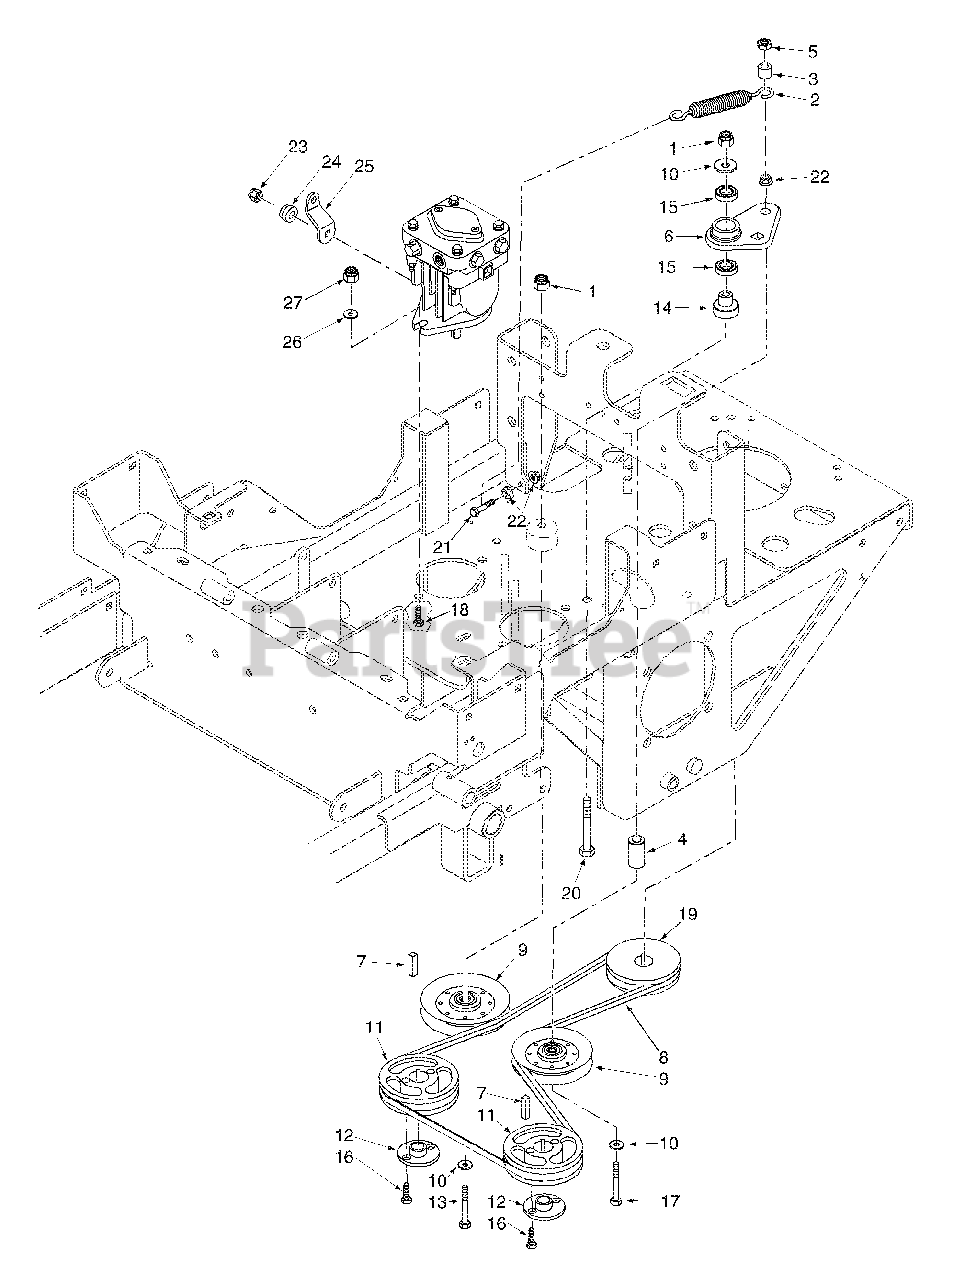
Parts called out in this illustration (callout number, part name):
1	Nut, Elastic Stop 3/8-16
2	Spring, SZC Pump Drive
3	Sleeve
4	Spacer, Pump Idler
5	Nut, Center Lock 3/8-16
6	Idler Arm Assembly, Pump Drive
7	Key, 5 x 5 x 25mm
8	Belt, Pump Drive SZC
9	Pulley, Idler 3" Dia.
10	Flatwasher, 3/8-.391 x .938 x .105 HD
11	Pulley, 5.45 O.D. Tapered Bore
12	Hub, Tapered, 15mm Bore
13	Bolt, Hex Head 3/8-16 x 2"
14	Pivot, Idler Short
15	Bearing
16	Bolt, Hex Head 1/4-20 x 1" Grade 8 Black
17	Bolt, Hex Head 3/8-16 x 3-1/4"
18	Bolt, Hex Head 3/8-16 x 1-1/2"
19	Pulley, 5.45" Dia. 1" Bore
20	Bolt, Hex Head 3/8-16 x 2-1/2"
21	Bolt, Hex Head 3/8-16 x 1-1/4 Grade 8 Black
22	Nut, Serr. Flange 3/8-16
23	Nut, Center Lock 5/16-24
24	Retainer, Pump Lever
25	Control Lever, Pump
26	Flatwasher, 3/8-.391 x .938 x .105
27	Nut, Elastic Stop 3/8-16
